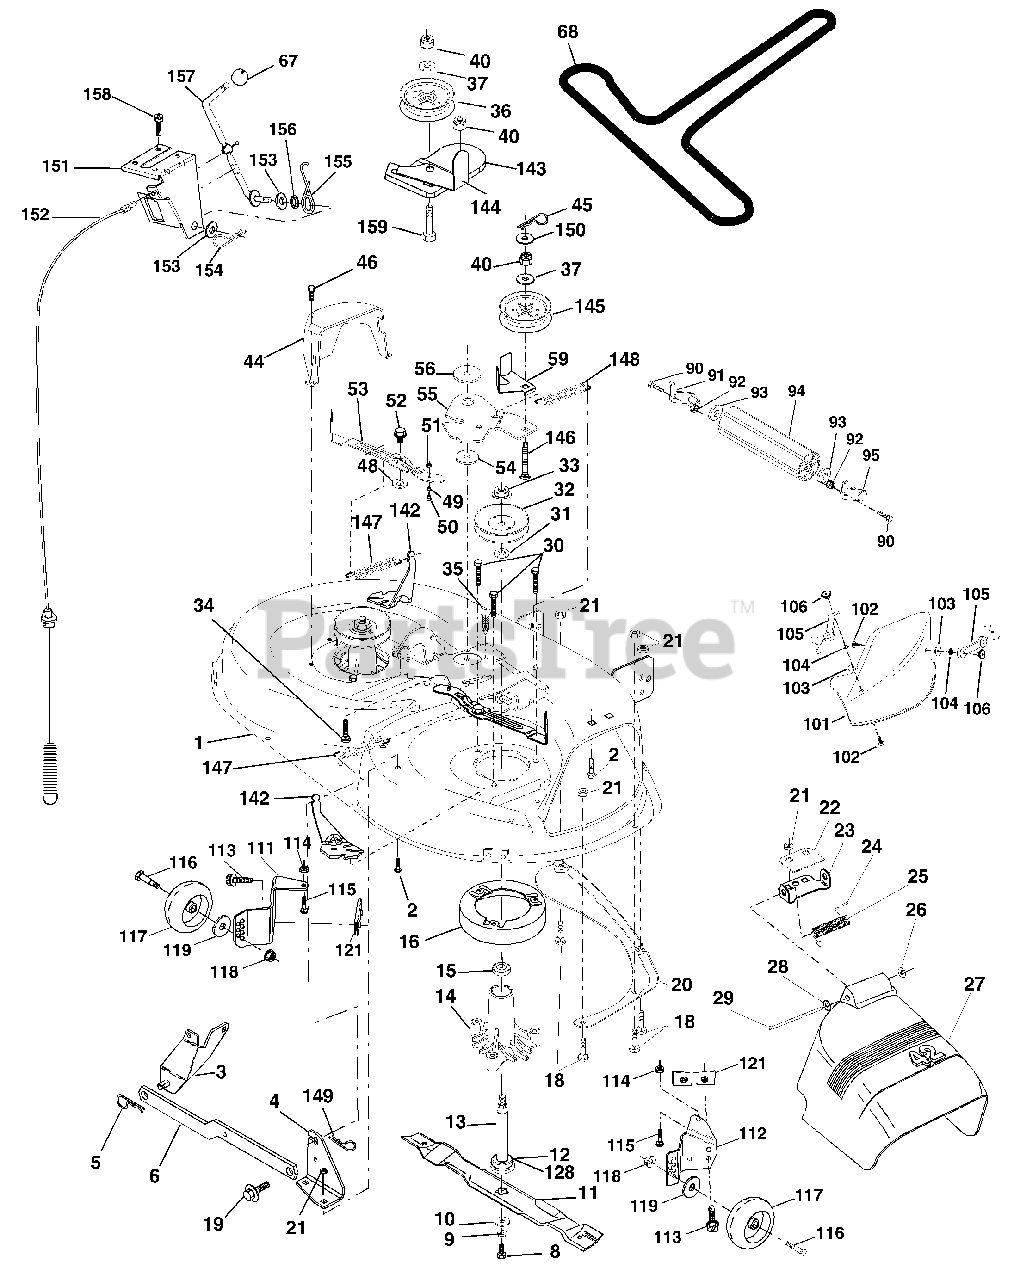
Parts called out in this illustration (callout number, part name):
1	Mower Deck Assembly, 42"
2	Bolt
3	Bracket Asm Fr. Sway Bar 3/42
4	Bracket Asm Deck 42" Sway Bar
5	Retainer Spring
6	Arm, Suspension, Rear
8	Bolt 3/8-24 x 25 Grade 8 patched
9	Washer, Lock
10	Washer, Hardened
11	Blade, Mulching 42" Std
11	Blade Mower 42" Hi-Lift Std
12	Bearing, Ball #6204
13	Shaft Assembly, Mandrel, Vented
14	Housing, Mandrel, Vented
15	Bearing, Ball, Mandrel
16	Stripper, Vented Mower Deck
18	Bolt, Carriage 5/16-18 x 5/8
19	Bolt, Shoulder
20	Baffle, Vortex
21	Nut
22	Stiffener Bracket
23	Bracket, Deflector Mower 42"
24	Cap, Sleeve 80 x 112 Blk Mower
25	Spring, Torsion, Deflector 2 52
26	Nut, Push Phos & Oil
27	Shield, Deflector 42" Blk
28	Washer 11/32 x 5/8 x 16 Gauge
29	Rod, Hinge 42" 6 75 W/G
30	Screw Thdrol Washer Head
31	Washer, Spacer Mower Vented
32	Pulley, Mandrel
33	Nut, Toplock 9/16
34	Bolt
35	Fastener, Christmas Tree
36	Pulley, Idler, Flat
37	Washer 13/32 x 13/16 x 16 Gauge
40	Nut
44	Guard, Mandrel, LH
45	Retainer
46	Screw, Thdrol 1/4-20 x 5/8 T
48	Washer, Hardened
49	Roller Assembly, Cam Follower
50	Bolt, Shoulder #10-24 Grade 5
51	Locknut
52	Bolt, Shoulder 5/16-18 UNC
53	Arm Assembly, Pad, Brake
54	Washer, Hardened
55	Arm, Idler
56	Spacer, Retainer
59	Guard TUV Idler
67	Knob Round
68	V-Belt, 42" Mower
90	Bolt Fin Hex 3/8-16 Unc x 1
91	Bracket Asm Noseroller LH
92	Nut, Lock, Hex W/Ins 3/8-16 UNC
93	Washer 17/3 x 7/8 x 6 Ga.
94	Roller Nose 38 & 42
95	Bracket Asm Noseroller RH
101	Mulcher Cover
102	Screw
103	Washer, Flat
104	Washer, Lock
105	Latch Assembly
106	Nut, Weld
111	Bracket, Gauge, Wheel LH
112	Bracket, Gauge, Wheel RH
113	Screw 5/16 - 18 x 3/4
114	Nut, Keps 5/16 - 18 UNC
115	Bolt, Carriage 5/16-18 x 1/2
116	Bolt, Shoulder
117	Wheel, Gauge
118	Nut Centerlock 3/8-16
119	Washer 3/8 x 7/8 x 14 Ga.
121	Bracket, Extruded
128	Washer, Felt
142	Arm Spring Brake Mower
143	Bracket Arm Idler 42"
144	Keeper Belt 42" Clutch Cable
145	Pulley Idler Flat
146	Bolt Carriage Idler
147	Spring Extension
148	Spring Return Idler
149	Retainer Spring Yellow
150	Washer 9/32 x 3/4 x 16 Ga.
151	Bracket Clutch Cable
152	Clutch Cable 42"
153	Washer Flat 3/8" Type B
154	Spring Retainer
155	Spring Retention LVR CLTCH CAB
156	Spacer Clutch Cable
157	Rod Clutch Cable 3/8"
158	Screw Hex Thd Cut 1/4-20 x 5/8
159	Bolt Rdhd Sqn 3/8-16 UNC x 1-3/4
